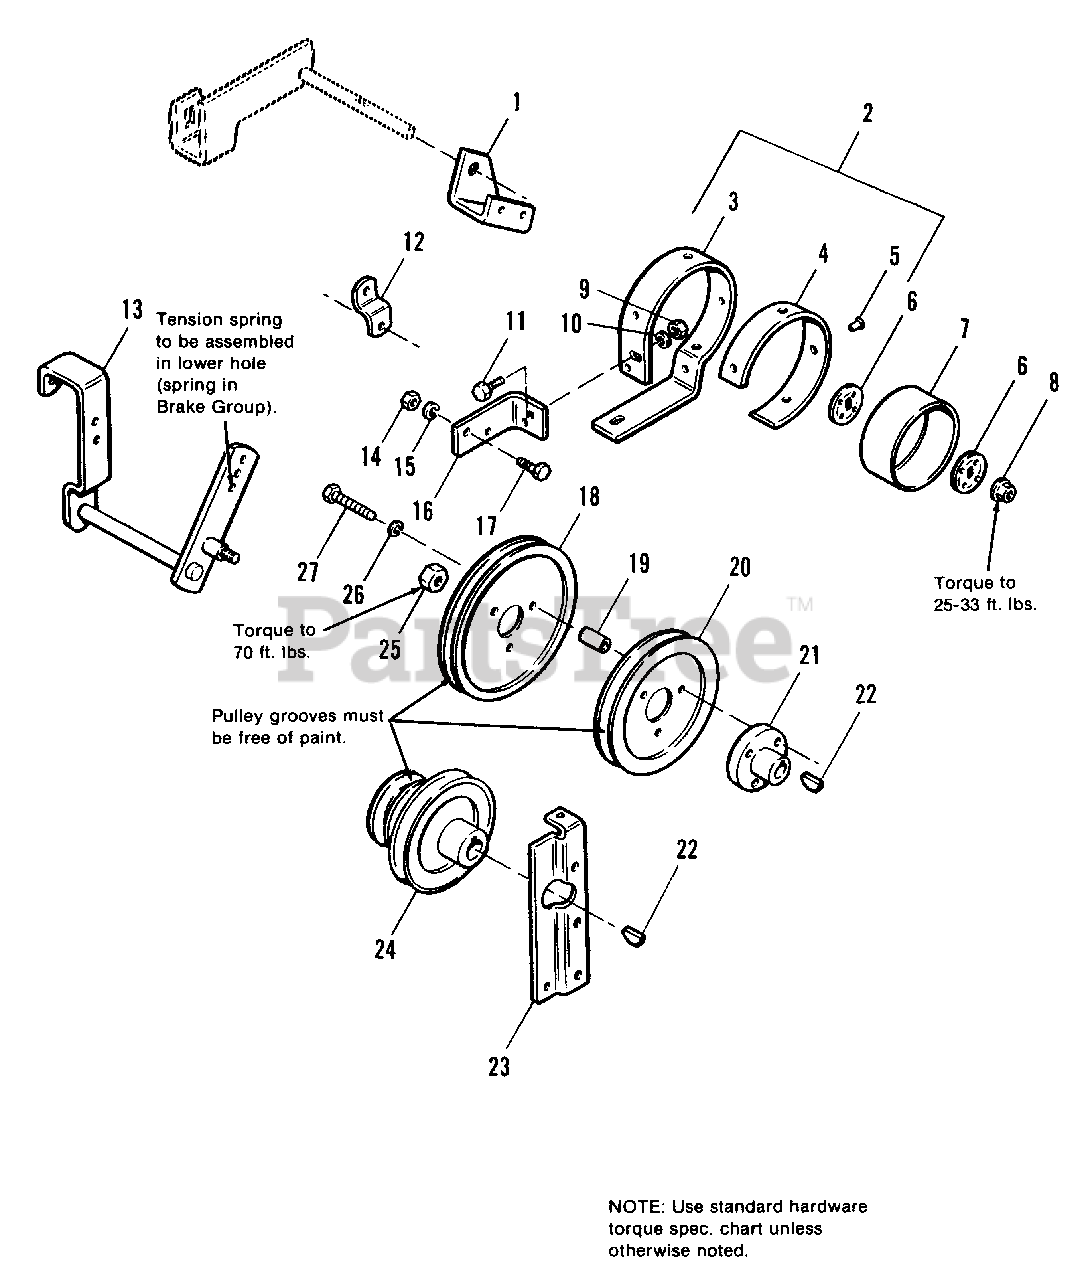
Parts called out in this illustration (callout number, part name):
1	BEARING, Idler
2	BAND ASSY., Brake
4	LINING, Brake
5	RIVET, Tubular, 3/16 x 5/16
6	WASHER, Special
7	DRUM, Brake
8	LOCKNUT, Hex, Flange, 7/16-14
9	NUT, Hex, Full, 1/4-20
10	LOCKWASHER, 1/4
11	CAPSCREW, Hex Hd., 1/4-20 x 3/4
12	CLIP, Spring
13	LEVER ASSY., Pivot
14	NUT, Hex, Full, 3/8-16
15	LOCKWASHER, 3/8
16	BRACKET, Brake Rod
17	CAPSCREW, Hex Hd., 3/8-16 x 1-1/4
21	HUB, Pulley
22	KEY, Woodruff, #9
23	SUPPORT, Belt Retainer
24	PULLEY ASSY., Front
25	LOCKNUT, Hex, Jam, 3/4-16
26	LOCKWASHER, 5/16
27	CAPSCREW, Hex Hd., 5/16-18 x 2
